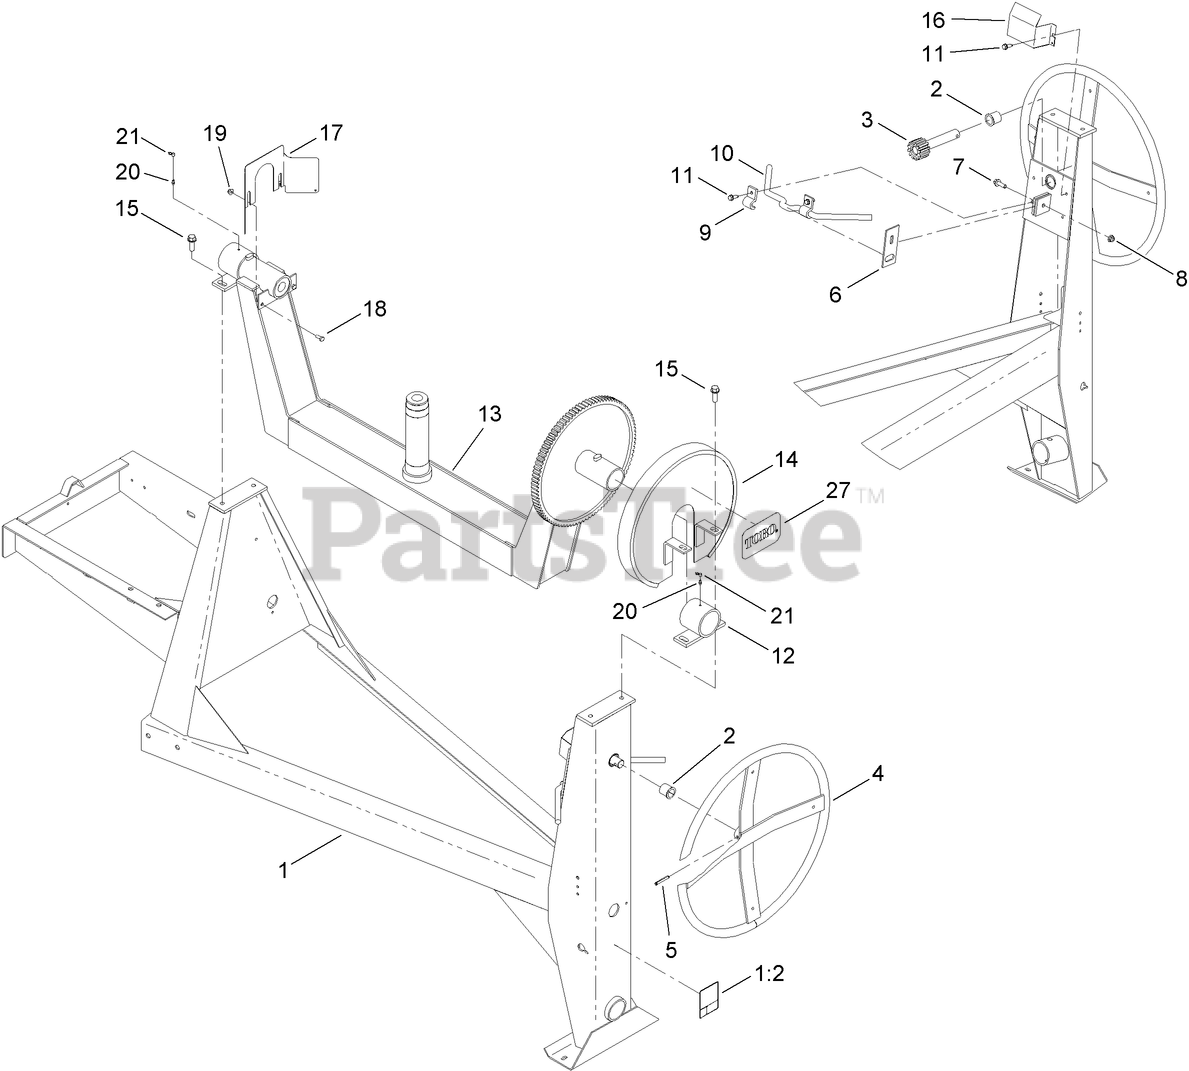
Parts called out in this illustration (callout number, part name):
1	FRAME ASM
1:2	DECAL-SAFETY CHAIN, TOWING
2	BUSHING-NYLON
3	SHAFT-TILT
4	HANDWHEEL
5	PIN-ROLL
6	DOG-BRAKE
7	SCREW-HHF
8	NUT-HF, NI
9	BRACKET-HANDLE
10	HANDLE-BRAKE
11	SCREW-HWHTF
12	TRUNNION
13	YOKE ASM
14	GUARD-BRAKE, UPPER
15	SCREW-HWH
16	GUARD-BRAKE, LOWER
17	GUARD-PINION
18	SCREW-HH
19	NUT-HF, NI
20	FITTING-GREASE
21	CAP-PLUG
27	DECAL
